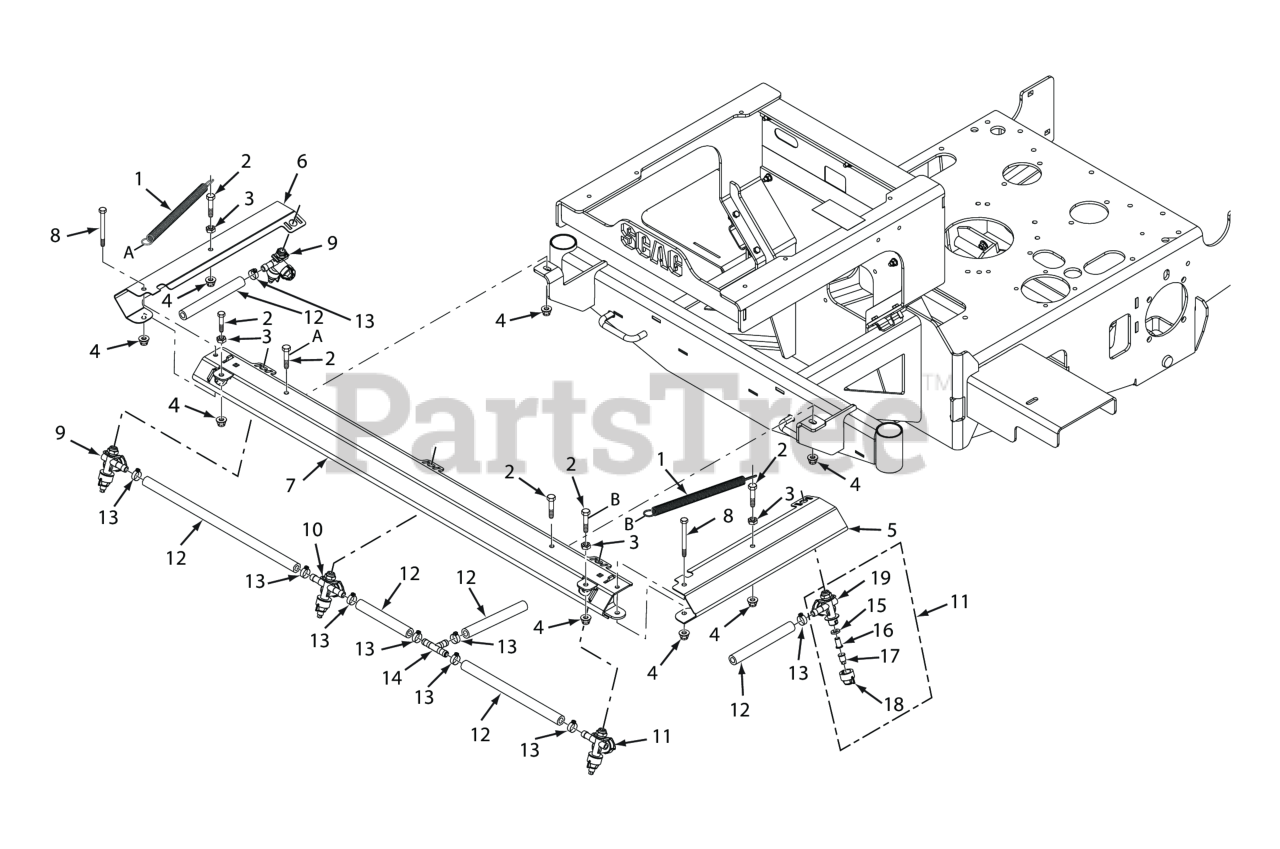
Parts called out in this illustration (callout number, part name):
1	Spring, Boom Arm
2	Bolt, Hex Head 3/8 - 16 x 1.50 - Stainless Steel
3	Nut, 3/8 - 16 - Stainless Steel
4	Nut, Flange Elastic Stop 3/8 - 16 - Stainless Steel
5	Boom, LH
6	Boom, RH
7	Boom, Main
8	Bolt, Hex Head 3/8- 16 x 3.50 - Stainless Steel
9	Nozzle Assembly, RH
10	Nozzle Assembly, Main
11	Nozzle Assembly, LH
12	Hose, 1/2" EPDM (order by the inch)
13	Clamp, Cable 3/4" I.D.
14	Fitting, Tee 1/2" Hose Barb
15	Washer, Rubber
16	Nozzle, Strainer #50 Mesh
17	Nozzle Tip
18	Nozzle Cap
19	Nozzle Body, Single LH (used in #11)
